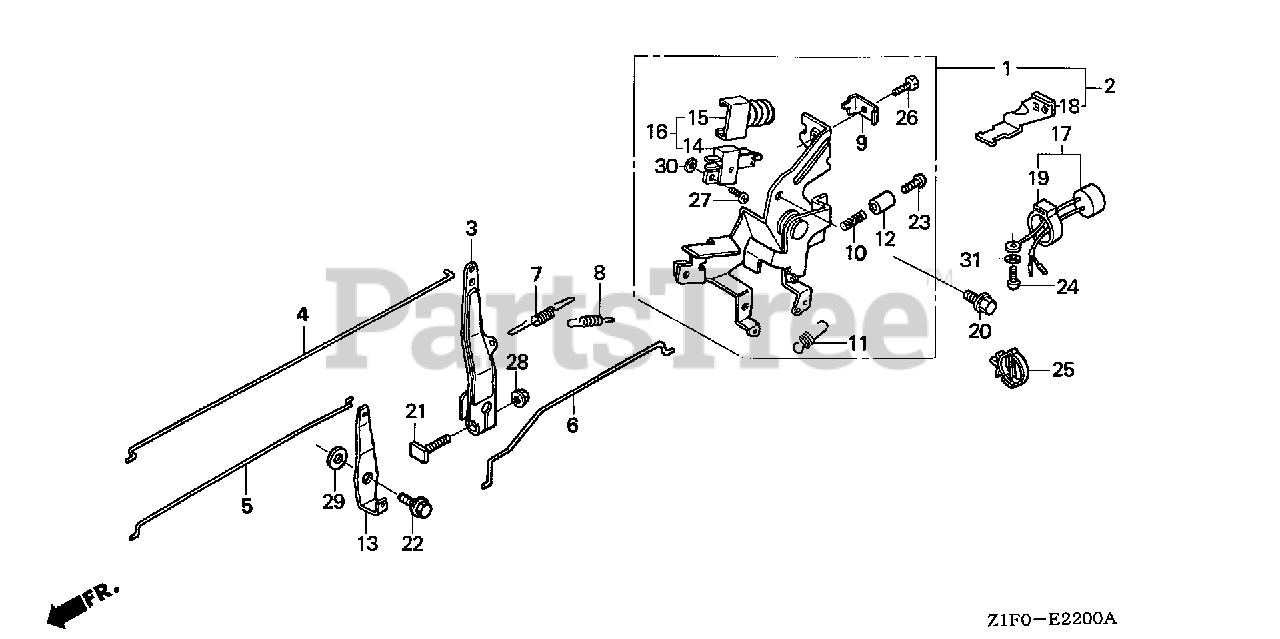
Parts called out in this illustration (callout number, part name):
2	CONTROL ASSY.
3	ARM, GOVERNOR
4	ROD, GOVERNOR
5	ROD, CHOKE
6	ROD, JOINT
7	SPRING, GOVERNOR
8	SPRING, GOVERNOR PRIMARY
9	HOLDER, CABLE
10	SPRING, CONTROL ADJUSTING Use from Engine SN 2327377.
11	SPRING, CABLE RETURN
13	LEVER, CHOKE JOINT
14	SWITCH ASSY., ENGINE
15	COVER, SWITCH
16	SWITCH ASSY., ENGINE STOP
17	BUZZER ASSY.
18	STAY, BUZZER
19	SUSPENSION, AUDIBLE PILOT
20	BOLT, FLANGE (6X12) (CT200)
21	BOLT, GOVERNOR ARM
22	BOLT, FLANGE (6MM)
23	SCREW, PAN (5X20)
24	SCREW, TAPPING (5X8)
25	CLIP, WIRE HARNESS
26	BOLT, RECESSED (5X16)
27	SCREW, PAN (4X14)
28	NUT, FLANGE (6MM)
29	WASHER, PLAIN (6MM)
30	WASHER, SPRING (4MM)
31	WASHER, SPRING (5MM)
